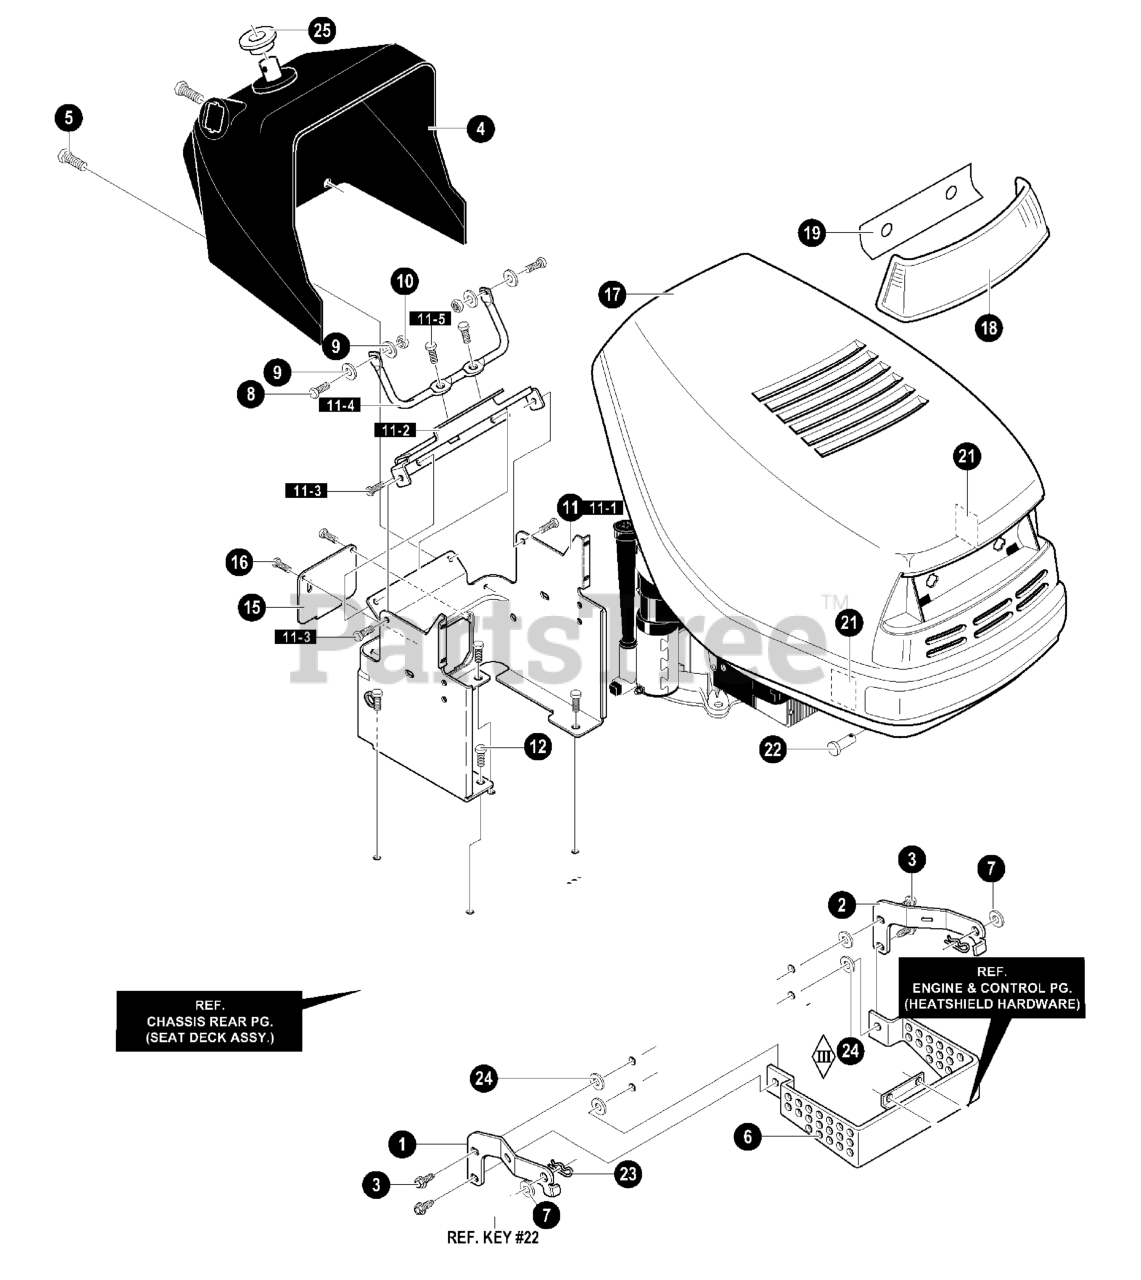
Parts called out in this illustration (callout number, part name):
1	BRACKET, HOOD RH
2	BRACKET, HOOD LH
3	SCREW, 5/16-18 x 0.75
4	DASH
5	SCREW,1/4-14X.75
6	HEAT SHIELD GUARD
7	WASHER, FLAT .375X.87 INSULATE
8	SCREW, 1/4-20X .75 HHC
9	WASHER, FLAT .286X .63X.065
10	NUT, 1/4-20 REGHEXCTRLK
11	ASSEMBLY, LOWER CONSOLE
11-1	TOWER, LOWER DASH
11-2	SUPPORT, STEERING
11-3	SCREW, 1/4-20X .50
11-4	ROD, DASH BRACE
11-5	SCREW, 1/4-20X .50
12	SCREW, 5/16-18 x 0.75
15	PANEL, ACCESS
16	SCREW, 10-24X.5
18	LENS, HEADLAMP
19	FOIL, LENS
21	FOIL, HEAT REFLECTOR
22	PIN,CLEVIS
23	PIN,HAIR
24	WASHER, FLAT .375X.87 INSULATE
25	BUSHING, STEERING SHAFT
